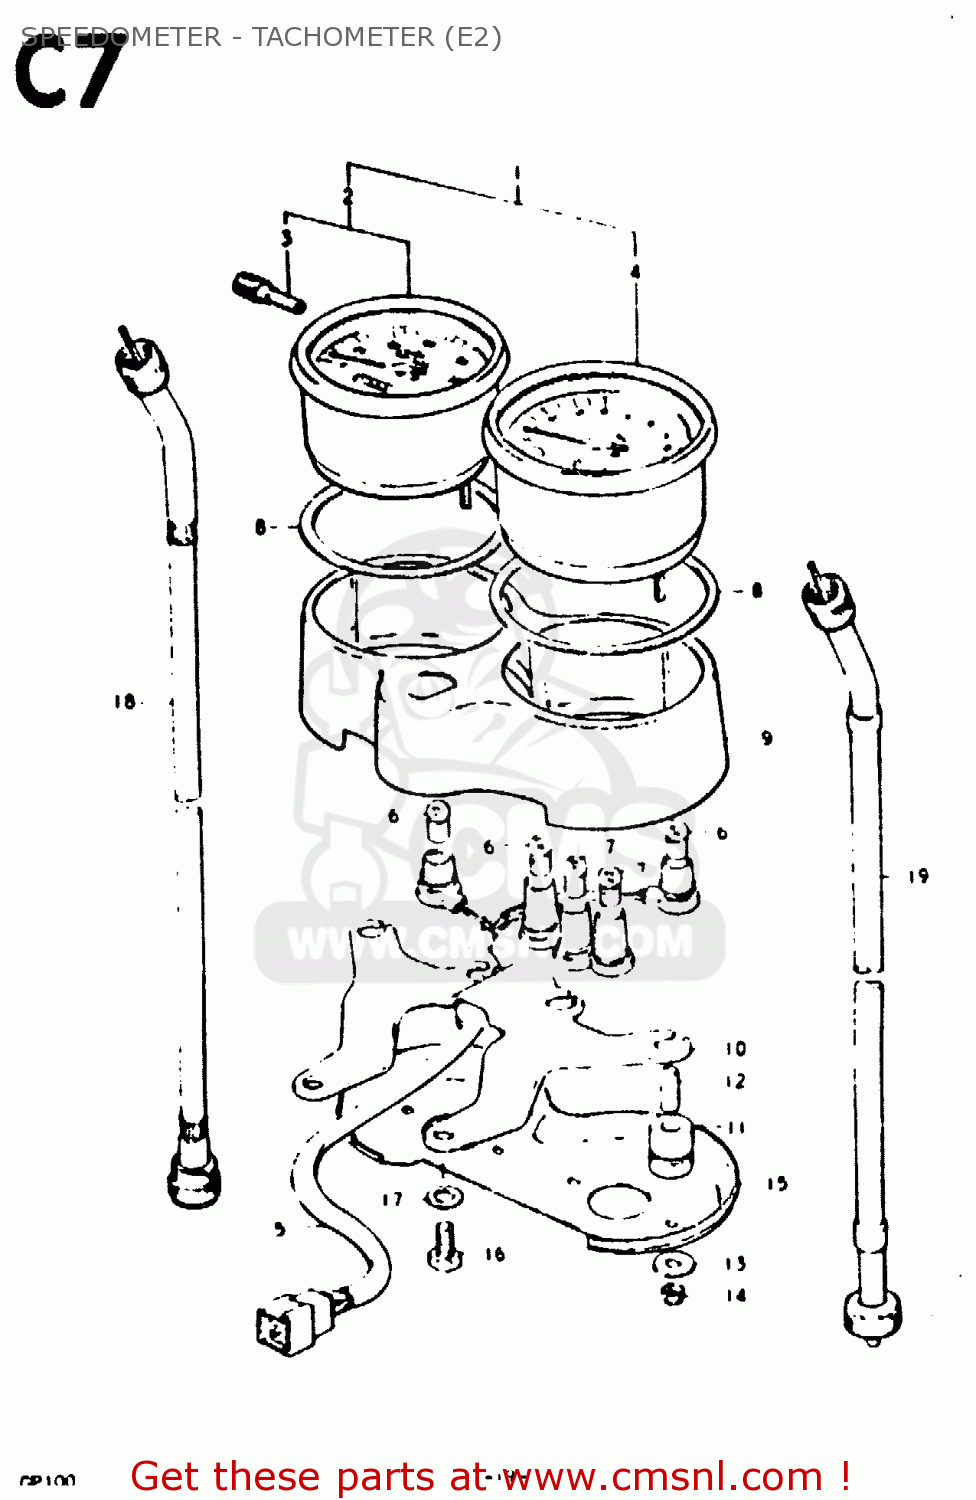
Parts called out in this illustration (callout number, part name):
1	SPEEDOMETER & TACHOMETER ASSY
2	SPEEDOMETER ASSY
3	KNOB,TRIP METER
4	TACHOMETER ASSY
5	SOCKET
6	BULB(6V1.7W,STANLEY,A61A)
7	BULB(6V/3W)
8	GASKET, METER
9	CASE, METER
10	BRACKET
11	CUSHION
12	SPACER
13	WASHER,METER
14	NUT
15	UNDER PLATE
16	BOLT 8X12
17	WASHER
18	CABLE ASSY, SPEEDOMETER
19	CABLE ASSY, TACHOMETER
